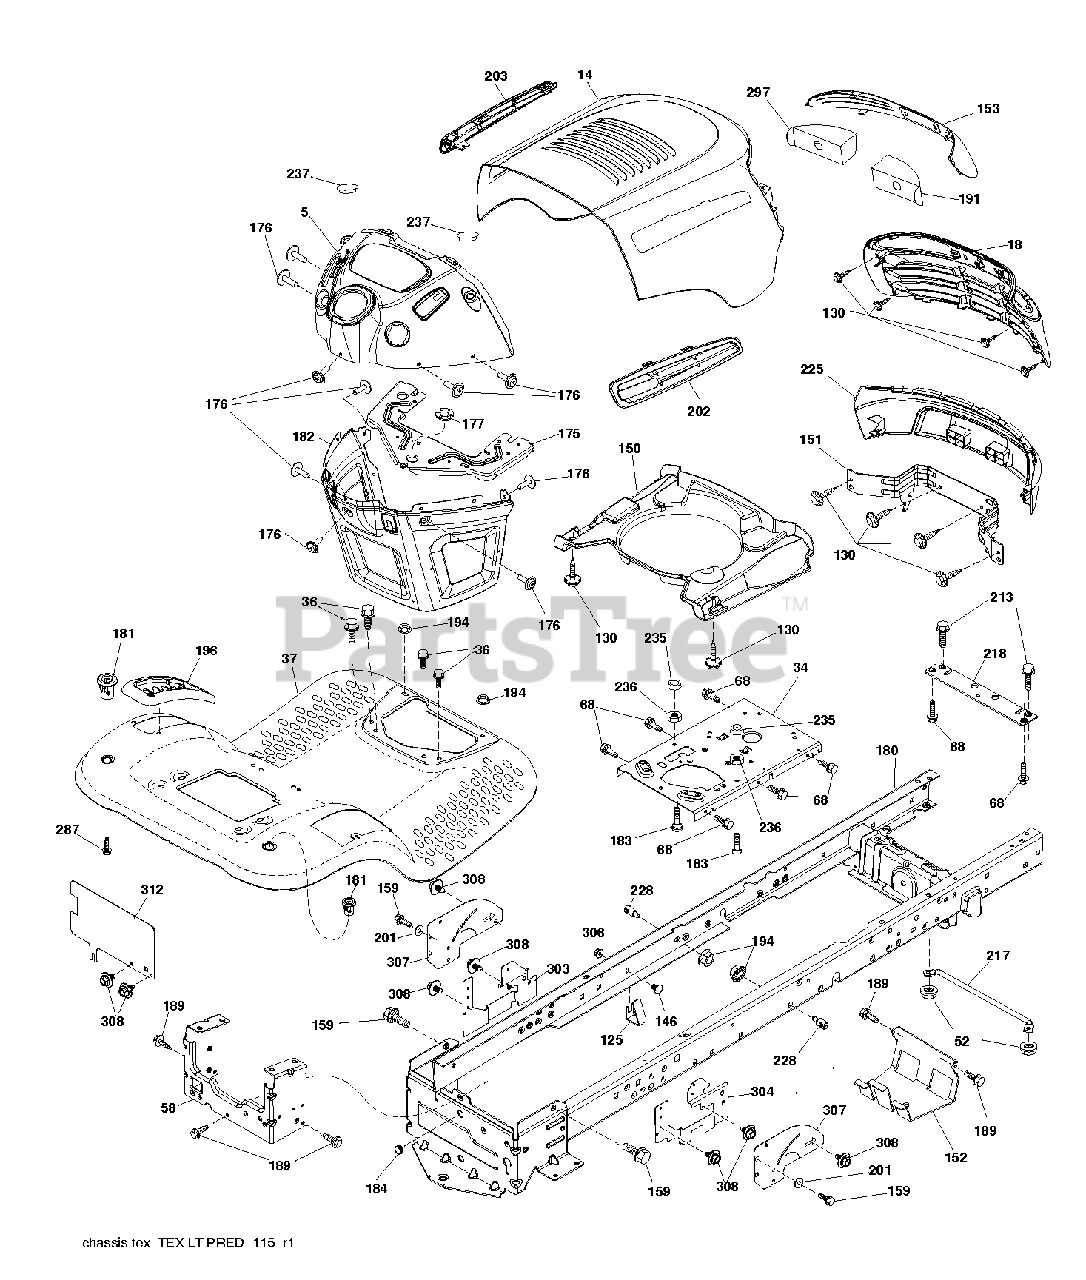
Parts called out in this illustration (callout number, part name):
36	SCREW 5/16"
52	LOCKNUT
58	DRAWBAR UPPER 2PC SMALL FENDER
125	Fuel Line Clip
130	SCREW.#10 X 0.750.BOS THREAD
146	BOLT.RDHD.SHT.SQNK.3
151	BRACKET.PIVOT.ALPHA.LT
152	SHIELD BROWNING
153	LENS.PREDATOR.LT
159	SCREW, 3/8-16X3/4
175	CROSSMEMBER
176	SCREW.#10-24X5/8.RN.QU
177	BUSHING STEERING
180	CHASS.WLDMNT.TL.12GA/2P.48/54
181	FEND/FTRST.PCH.CPH.NFW
182	DASH.LWER.PREDATOR/HUSQ.LT
183	BOLT.5/16-18X1-1/4 FULL THD
184	PLUG.DEMO.625
189	SCREW
191	INSERT.REFLECT.PREDATOR.LT.RH
194	NUT LOCK HEX FLANGE 5/16-18
196	CONSOLE.ASM.DECKLFT.BL/RBT.TLT
201	WASHER
213	BOLT
217	ROD.PIVOT.HOOD
218	X-PIECE.HOOD.STOP.NON/
228	STUD.FASTNER.W/ANTI-ROTATE
235	SPACER FENDER
236	NUT.CENTERLOCK.5/16-
237	PLUG.MOUNT.CARGO.BLK
297	REFLECTOR.INSERT.PRED.LH.LT
304	SHIELD.LWR.RH.LT30DECK.PNT.BLK
306	NUT LOCK FLG 3/8-16 UNC
308	BOLT, 5/16-18 X 1 3/4
